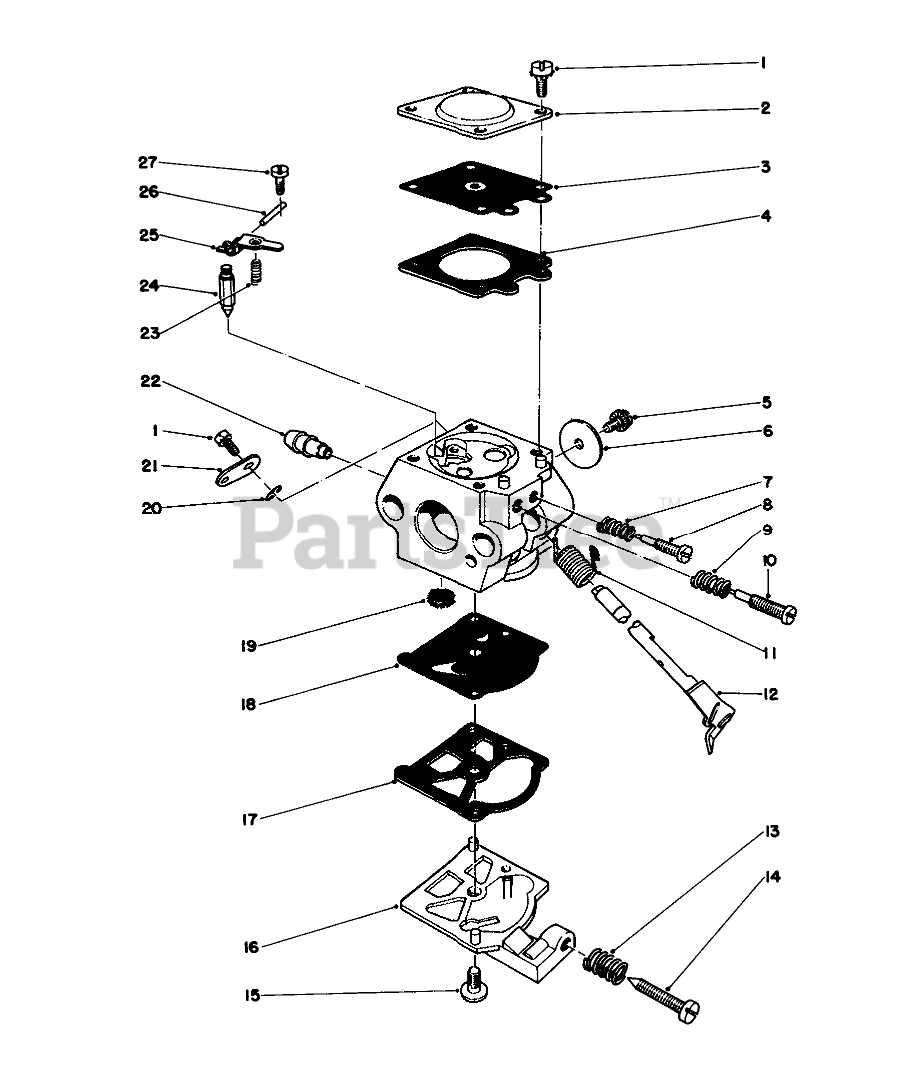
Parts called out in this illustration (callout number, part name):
1	Screw
2	Cover, Diaphragm
3	METERING DIAPHRAGM
4	Gasket-Metering Diaphragm
5	VALVE SCREW
6	Valve-Throttle
7	Spring-Needle (Idle)
8	Needle-Idle
9	Spring-Needle (Hi)
10	Needle Hi Speed
11	Spring-Throttle Return
12	Shaft Assembly-Throttle
13	Spring-Idle Screw
14	Screw-Idle Adjust
15	Screw
16	Cover-Fuel Pump
17	PUMP GASKET
18	PUMP DIAPHRAGM
19	Inlet Screen
20	Ring-Throttle Retainer
21	Lever-Throttle
22	Fitting Fuel Inlet
23	Metering Lever Spring
24	NEEDLE VALVE
25	Lever Metering
26	Metering Lever Pin
27	Screw-Metering Pin
